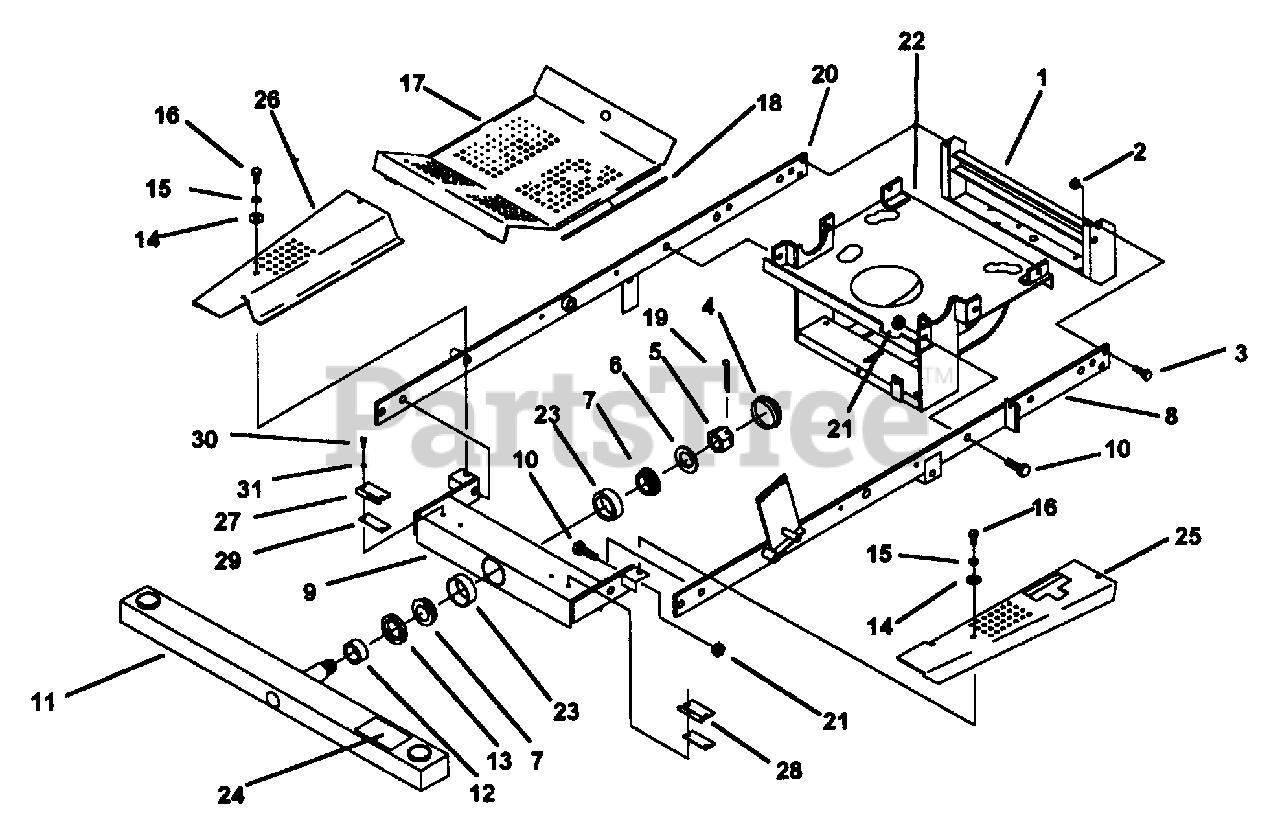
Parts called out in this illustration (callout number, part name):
1	REAR BUMPER WELDMENT
2	NUT, 3/8-16 NYLOC
3	BOLT, 3/8-16 X 1-1/4" GR. 5
4	GREASE CAP
5	CASTLENUT, HEX. 1"-14
6	WASHER, 1" 10 GA.
7	BEARING CONE
9	FRONT CHANNEL WELDMENT
11	FRONT BUMPER/AXLE WELDMENT
12	BEARING SPACER
13	SEAL, OIL 1.688 SHAFT
14	WASHER, FLAT STD. 5/18"
15	LOCKWASHER, 5/16" HEAVY SPRING
16	BOLT, 5/16-18 X 3/4" GR. 5
17	FOOT DECK WELDMENT
19	COTTER PIN, 3/18 X 2"
21	NUT, 1/2-13, STOVER
23	BEARING CUP
24	DECAL, "FREEWHEEL MACHINE"
27	HINGE, R.H.
28	HINGE, L.H.
29	HINGE SHIM PLATE
30	BOLT, 1/4-20 X 3/4" GR. 5
31	LOCKWASHER, 1/4" SPLIT SPRING
